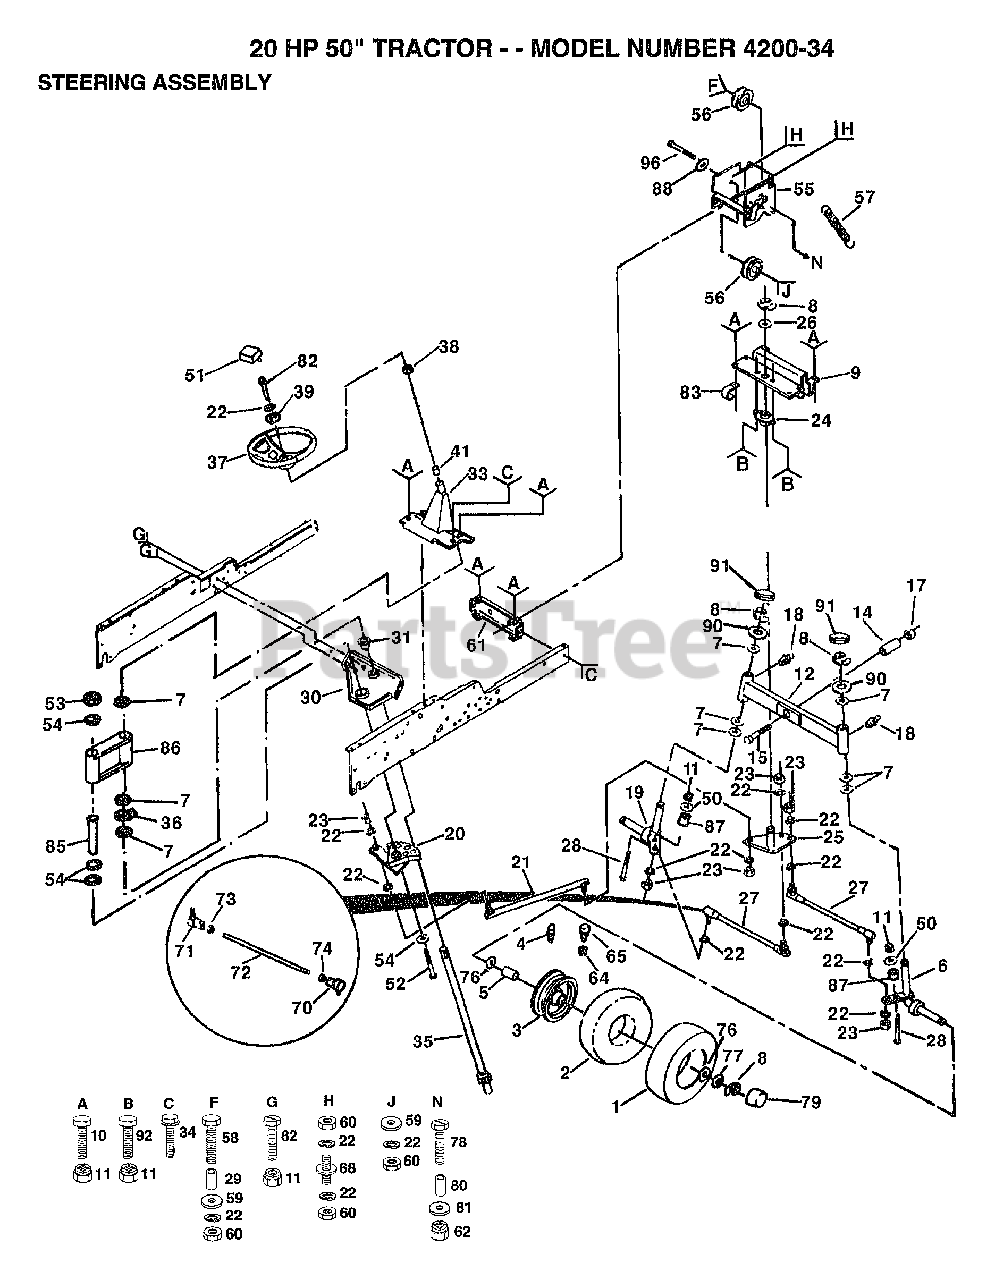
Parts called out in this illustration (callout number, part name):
2	TUBE.16X6.5/7.5-8
4	FITTING LT
5	"FLANGE, BEARING"
6	SPINDLE RH T
7	WASHER .T
8	RING
9	AXLE BRACKET T
14	SPACER BEARING
15	BOLT
17	LOCKNUT M
18	ZERK M
19	SPINDLE ASSY T
20	SECTOR T
21	LINK.DRAG.T
22	LOCKWASHER
25	"T, BELLCRANK"
26	WASHER
27	TIE ROD T
28	BOLT
29	SPLIT SPACER YTV
31	"FLANGE GT, BEAR."
33	SUPPORT ASSY T
34	SCREW
35	SHAFT STEERING GT
36	KLIP RING
38	ADAPTER LT
39	WASHER T
41	"T, BEARING"
50	WASHER T
51	"INSERT,STR WHEEL"
52	BOLT T
53	NUT LTV
54	WASHER GT
55	IDLER BRKT T
56	IDLER-INSIDE T
57	SPRING
58	BOLT
59	WASHER
60	NUT.HEX.3/8-16UNC
61	FRAME BRACKET GT
64	VALVE STEM LT
65	VALVE CAP
70	JOINT.RH
71	JOINT.LH
73	NUT
74	NUT
76	WASHER
77	WASHER
79	HUB CAP
80	BUSHING LT
81	WASHER
82	BOLT
83	CLIP GTV
85	TUBE T
86	COLLAR
87	SPACER LT
88	WASHER T
90	WASHER
91	CAP
92	BOLT
